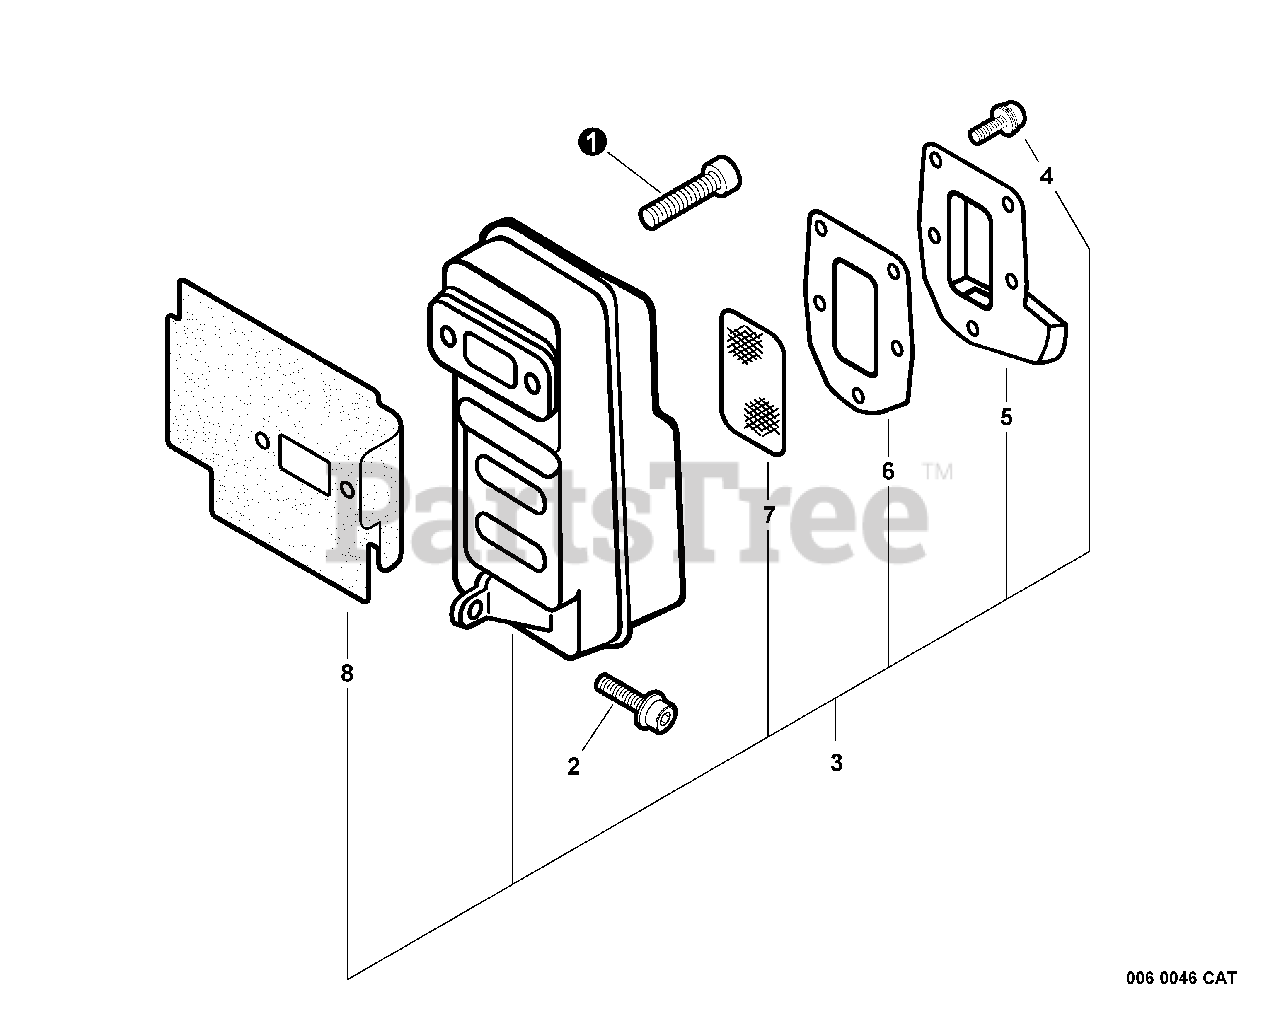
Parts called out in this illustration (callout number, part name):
1	SCREW - 6X20
2	SCREW - 5X16
3	MUFFLER ASSY
4	SCREW - 4X10
5	GUIDE, EXHAUST
6	GASKET, EXHAUST
7	SCREEN, SPARK ARRESTOR
8	SHIELD, EXHAUST
